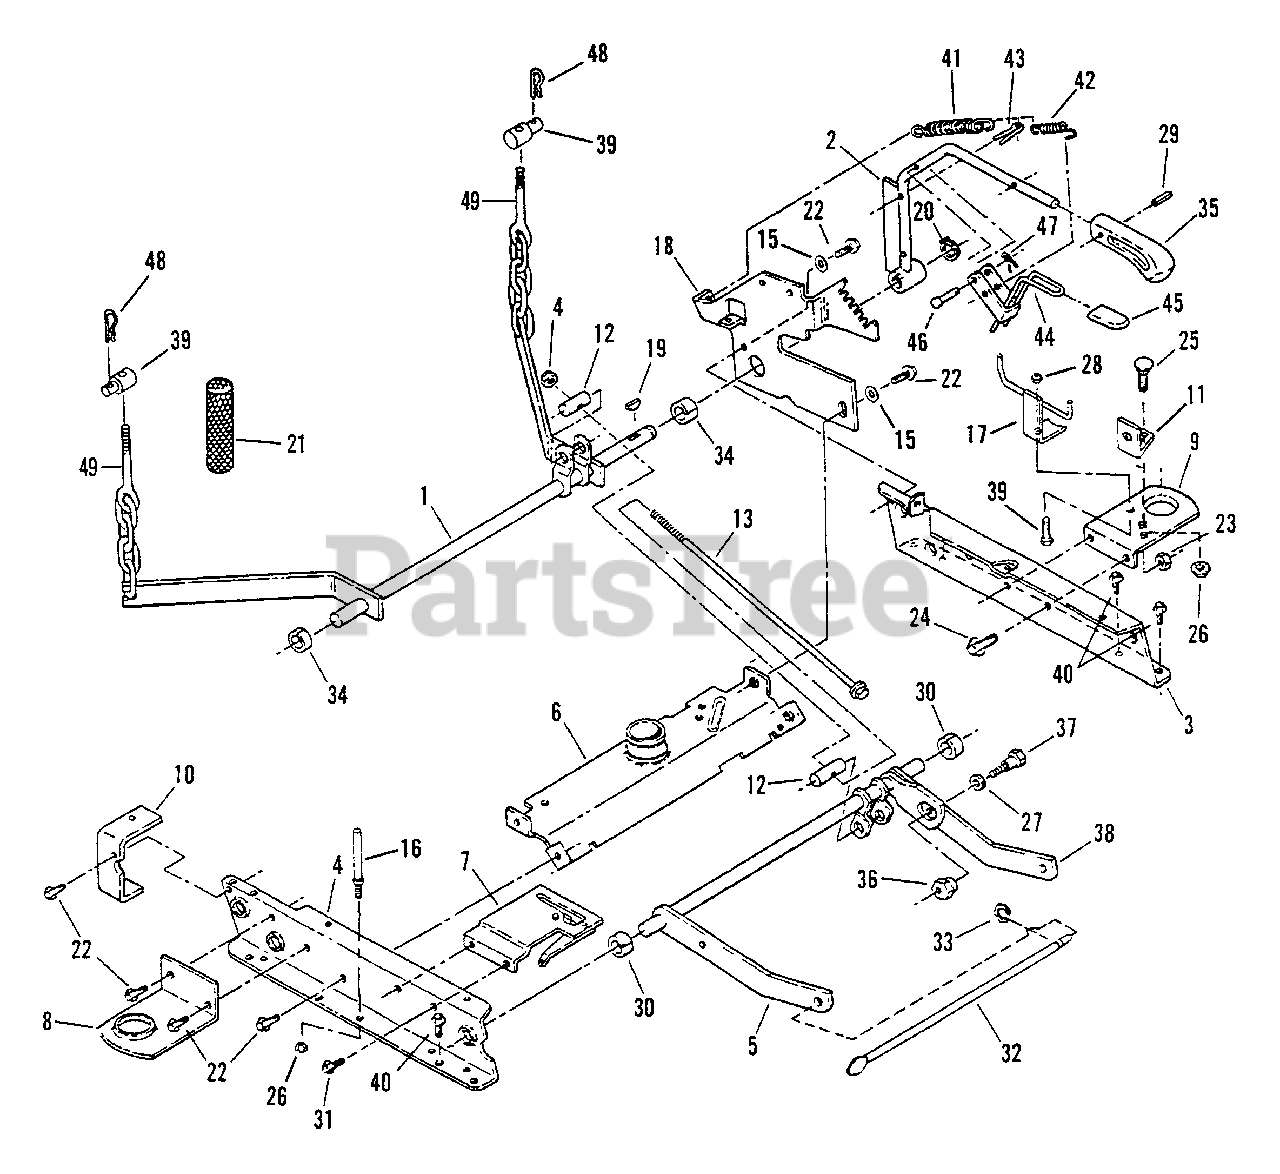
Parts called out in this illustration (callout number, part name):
1	ASSEMBLY, Rear Lift Arm
2	LEVER, Height Adjustment Lift
3	RAIL, Left Half
4	RAIL, Right Half
5	STRUCTURE, Front Lift Arm
6	BRACE, Weldment
7	ASSEMBLY, Clutch Plate
8	SPINDLE, Brace (Right)
9	SPINDLE, Brace (Left)
10	BRACKET, Cover
11	ANCHOR
12	CLEVIS, Timing Rod
13	ROD, Leveling (3/8-24 thread)
14	NUT, 3/8-24 Hex Top Lock
15	WASHER, 3/8 Internal Tooth Lock
16	GUIDE, Belt (Rod)
17	GUIDE, Belt (Structure)
18	QUADRANT, Lift Lever
19	KEY, 3/16 x 7/8" Woodruff
20	RING, 3/4 Retaining
21	COVER, Chain
22	SCREW, 3/8-16 x 3/4" Self-Tapping
23	NUT, 3/8-24 Hex Lock
24	SCREW, 3/8-24 x 3/4" Hex Cap
25	BOLT, 5/16-18 x 3/4" Carriage
26	NUT, 5/16-18 Hex Flange Lock
27	WASHER, 3/8 Internal Tooth Lock
28	NUT, 3/8-24 Hex Lock
29	PIN, 3/16 x 3/4" Roll
30	RING, Red
31	SCREW, 5/16-18 x 1/2" Self-Tapping
32	SUPPORT, Rod 7/16"
33	RING, Retaining
34	RING, Blue
35	GRIP, Height Adjustment Lever
36	ECCENTRIC, Leveling
37	BOLT, 3/8-24 x 3/4" Shoulder
38	ARM, Front Lift (Left Side)
39	SWIVEL, 3/8-16
40	BOLT, 5/16-18 x 5/8" Hex Flange Lock
41	SPRING, Extension
42	SPRING, Latch
43	PIN, 3/16 x 1-1/2" Cotter
44	LATCH
45	GRIP, Lift Latch
46	PIN, 1/4 x 1-1/4" Clevis
47	PIN, 1/16 x 3/4" Cotter
48	PIN, 3/32 x 1-1/2" Hair Cotter
49	EYE BOLT
